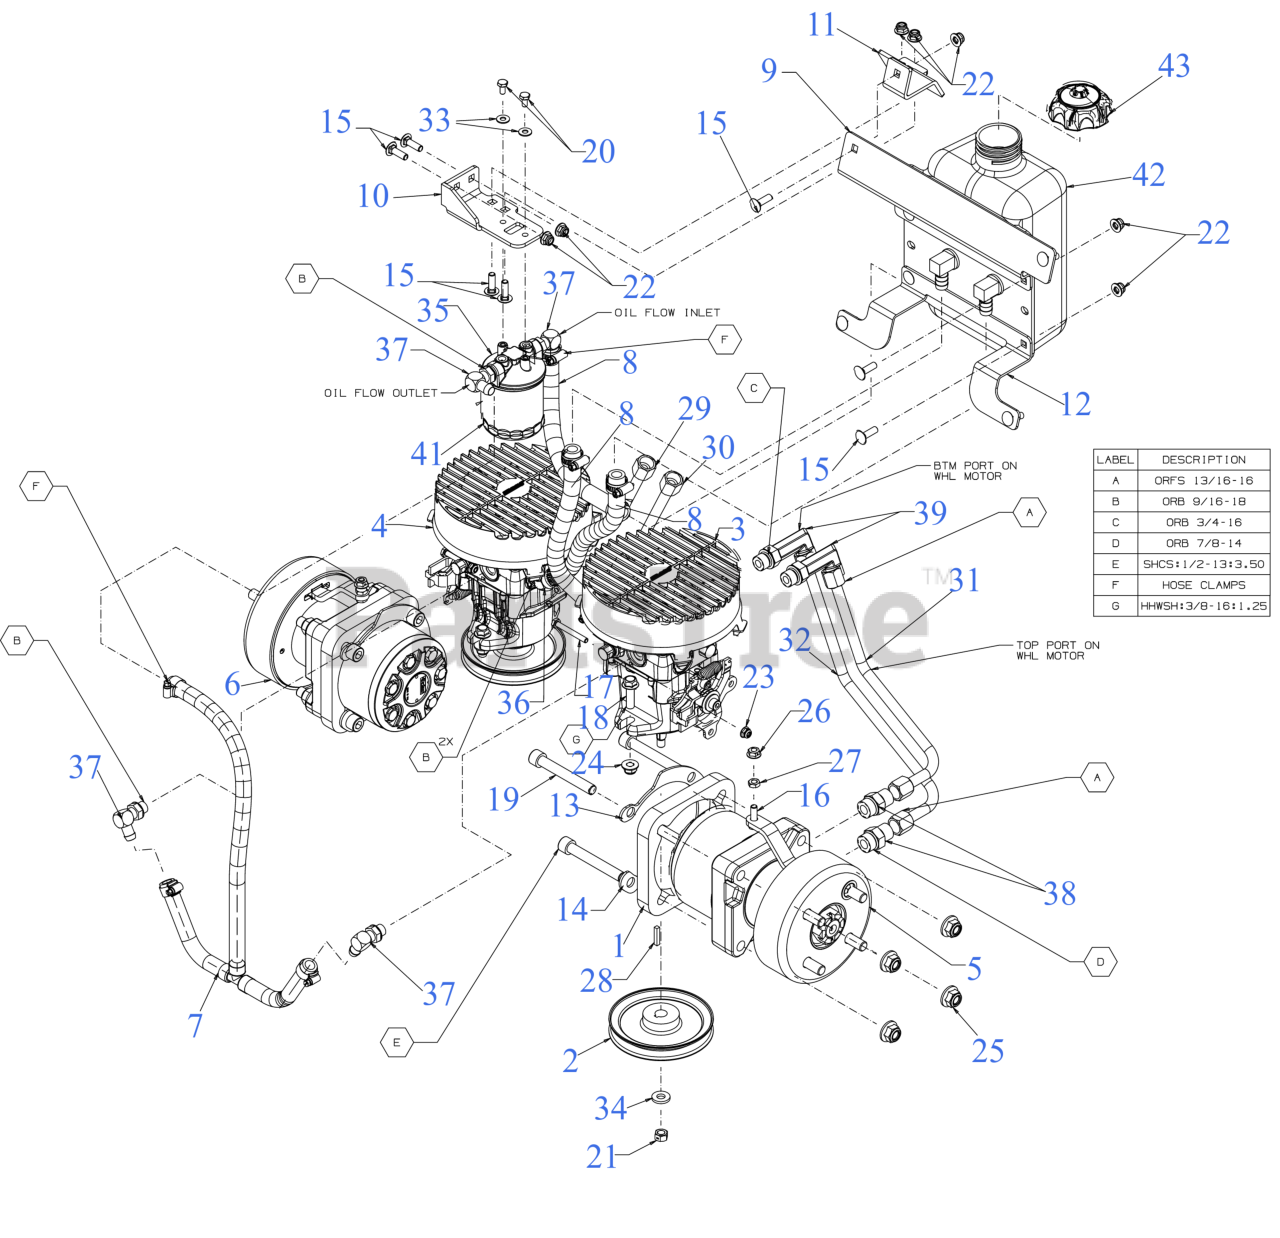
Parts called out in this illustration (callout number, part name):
1	WHEEL SPACER MOTOR
2	PULLEY-HYDRO PUMP
3	HYDRO PUMP (RH)
4	HYDRO PUMP (LH)
5	HYDRO MOTOR (RH)
6	HYDRO MOTOR (LH)
7	HYDRO DRAIN HOSE
8	HYDRO HOSE ASM 11"
9	OIL RESERVOIR BRACKET
10	FILTER MOUNT BRACKET
11	BRAKE CABLE MOUNT BRACKET
12	OIL RESERVOIR BRACKET (LOWER)
13	WHEEL MOTOR SHIM PLATE
14	WHEEL MOTOR LOWER SHIM PLATE
15	CARRIAGE BOLT 5/16-18 x 1.00
16	SCREW 5/16-18 x 1.0 GR5
17	SCREW 1/4-20 x 2 GR5
18	SCREW 3/8-16 x 1.25 GR5
19	HEX CAP SCREW 1/2"-13x3.5
20	SCREW 1/4-20X.5 GR5
22	FLANGE LOCK NUT 5/16-18
23	FLANGE LOCK NUT
26	HEX FLANGE NUT
28	SQUARE KEY 3/16 x 1.00
29	HYDRO TUBE (OUTSIDE/LH)
30	HYDRO TUBE (INSIDE/LH)
31	HYDRO TUBE (OUTSIDE/RH)
32	HYDRO TUBE (INSIDE/RH)
33	FLAT WASHER
34	FLAT WASHER
35	OIL FILTER ADAPTER
36	45 DEGREE FITTING (6 ORB X-8 BEAD)
37	ELBOW FITTING
38	HYDRO FITTING 8 ORFS x 10 ORB
39	ELBOW FITTING
41	HYDRAULIC FILTER
42	HYDRO OIL TANK (1 GAL)
43	HYDRO OIL TANK CAP
